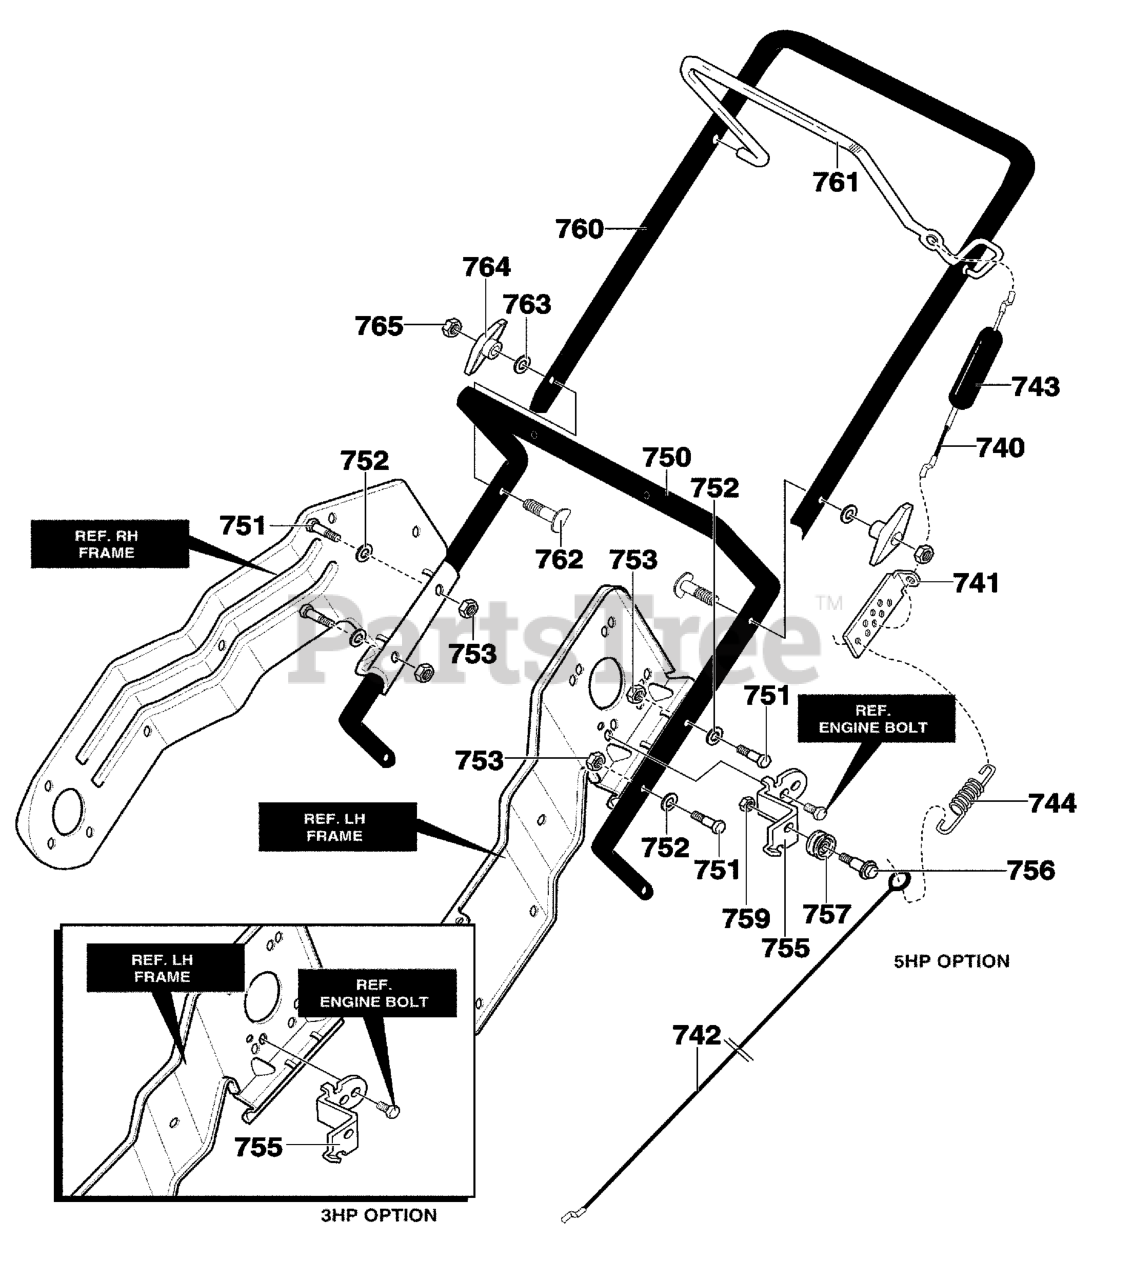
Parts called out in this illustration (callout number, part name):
740	CABLE, UPPER
741	BRKT, CABLE ADJ
742	CABLE LOWER CONTROL
743	BOOT, CLUTCH SPRING
750	HANDLE LOWER
751	SCREW, 1/4-20X1.25
752	WASHER, FLAT .281X.63X.065
753	NUT, 1/4-20
755	BRACKET, CABLE
756	BOLT, .375X.375 1/4-20
757	PULLEY, .906X.305
759	NUT, 1/4-20
760	HANDLE, UPPER
761	BAIL, CONTROL
762	BOLT, 5/16-18X2.00
763	WASHER, FORM
764	KNOB,T
765	NUT, 5/16-18
